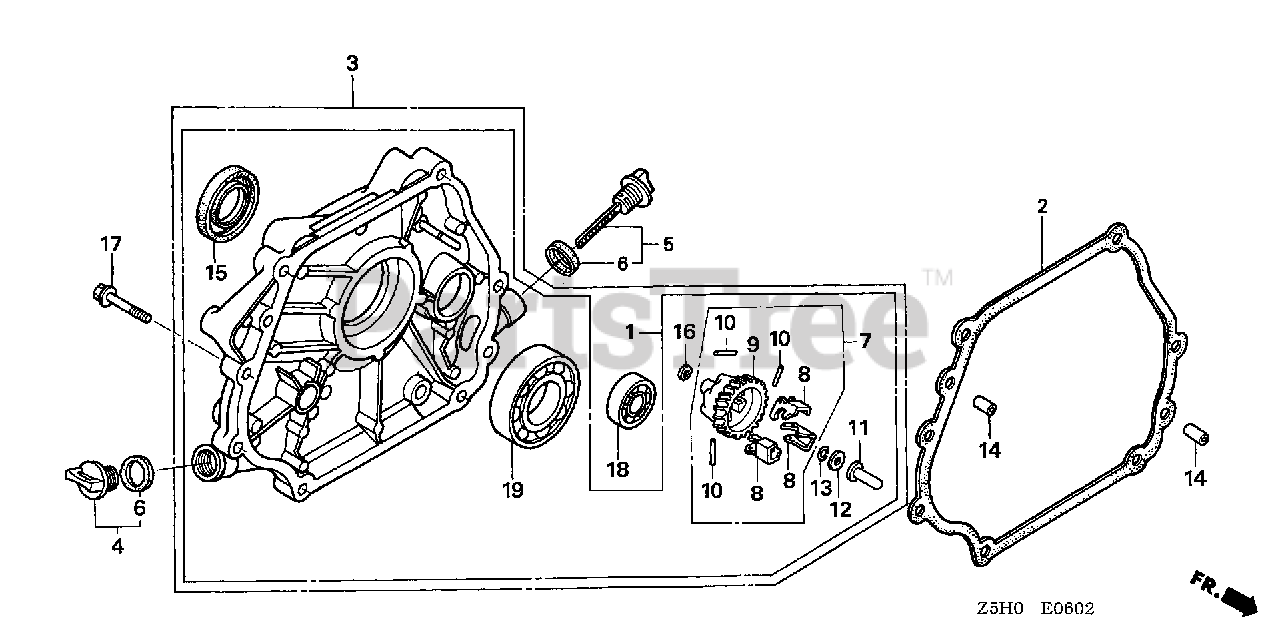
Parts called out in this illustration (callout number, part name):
1	COVER ASSY., CRANKCASE
2	GASKET, CASE COVER
4	CAP ASSY., OIL FILLER
5	CAP ASSY., OIL FILLER
6	GASKET, OIL FILLER CAP
7	GOVERNOR ASSY.
8	WEIGHT, GOVERNOR
9	HOLDER, GOVERNOR WEIGHT
10	PIN, GOVERNOR WEIGHT
11	SLIDER, GOVERNOR
12	WASHER (6X16)
13	CLIP, GOVERNOR HOLDER
14	PIN, DOWEL (8X12)
15	OIL SEAL (30X46X8)
16	WASHER, PLAIN (6MM)
17	BOLT, FLANGE (8X35)
19	BEARING, RADIAL BALL (6206)
